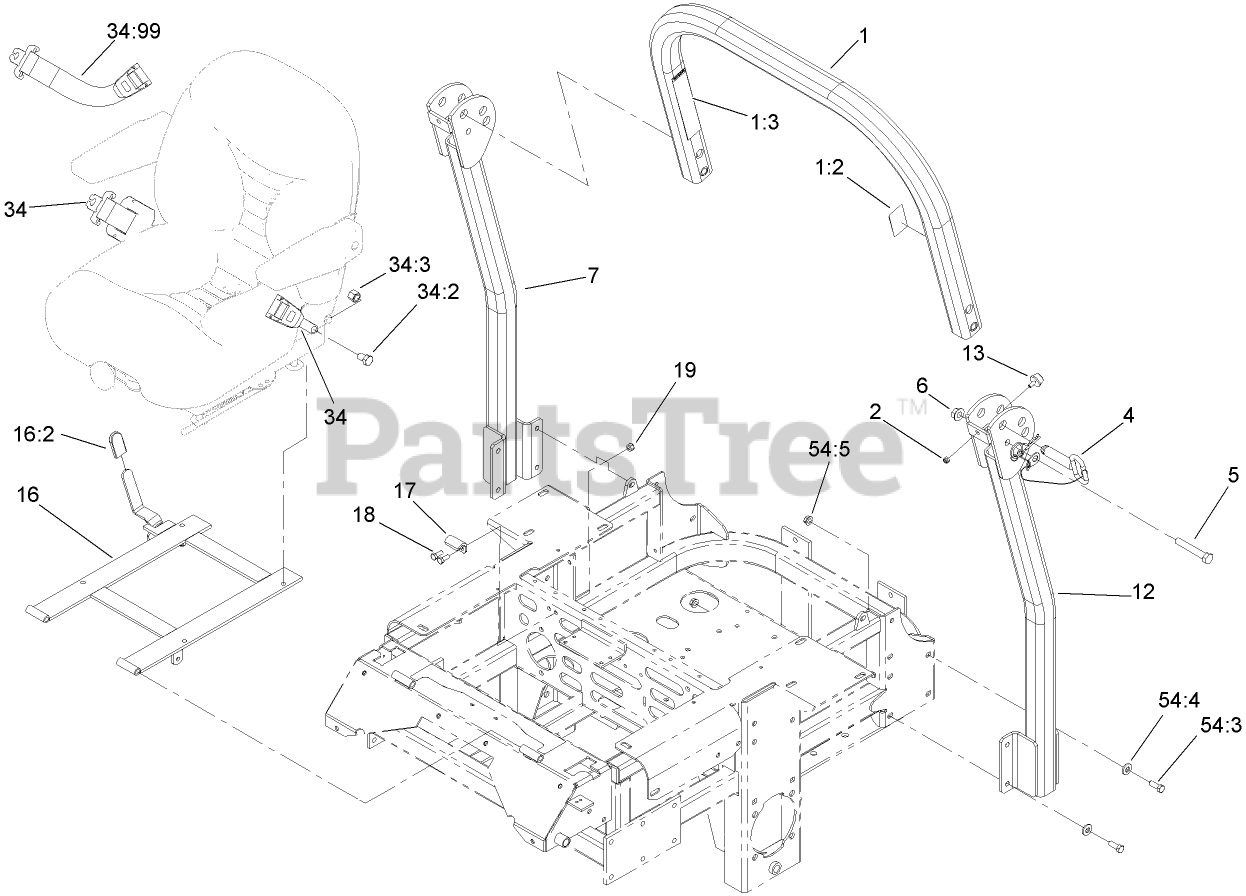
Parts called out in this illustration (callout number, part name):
1	Upper Tube ASM
1:2	DECAL-ROPS
1:3	DECAL-WARNING, FOLDING ROPS
2	NUT-LOCK, NI
4	PIN-FOLD, ROPS
5	SCREW-HH
6	NUT-HF
7	TUBE-SUPPORT, RH
12	TUBE-SUPPORT, LH
13	BUMPER-RUBBER
16	SEAT FRAME AND LATCH ASM
16:2	GRIP-LEVER
17	Catch-Latch, Seat
18	SCREW-HH
19	NUT-LOCK, NI
34	RETRACTABLE SEATBELT KIT
34:2	SCREW-HH
34:3	NUT-LOCK
34:99	SEAT BELT EXTENSION KIT
54	BAG-BOLT, ROPS
54:3	SCREW-HH
54:4	WASHER-BELLEVILLE
54:5	NUT-HHF, WHIZ
